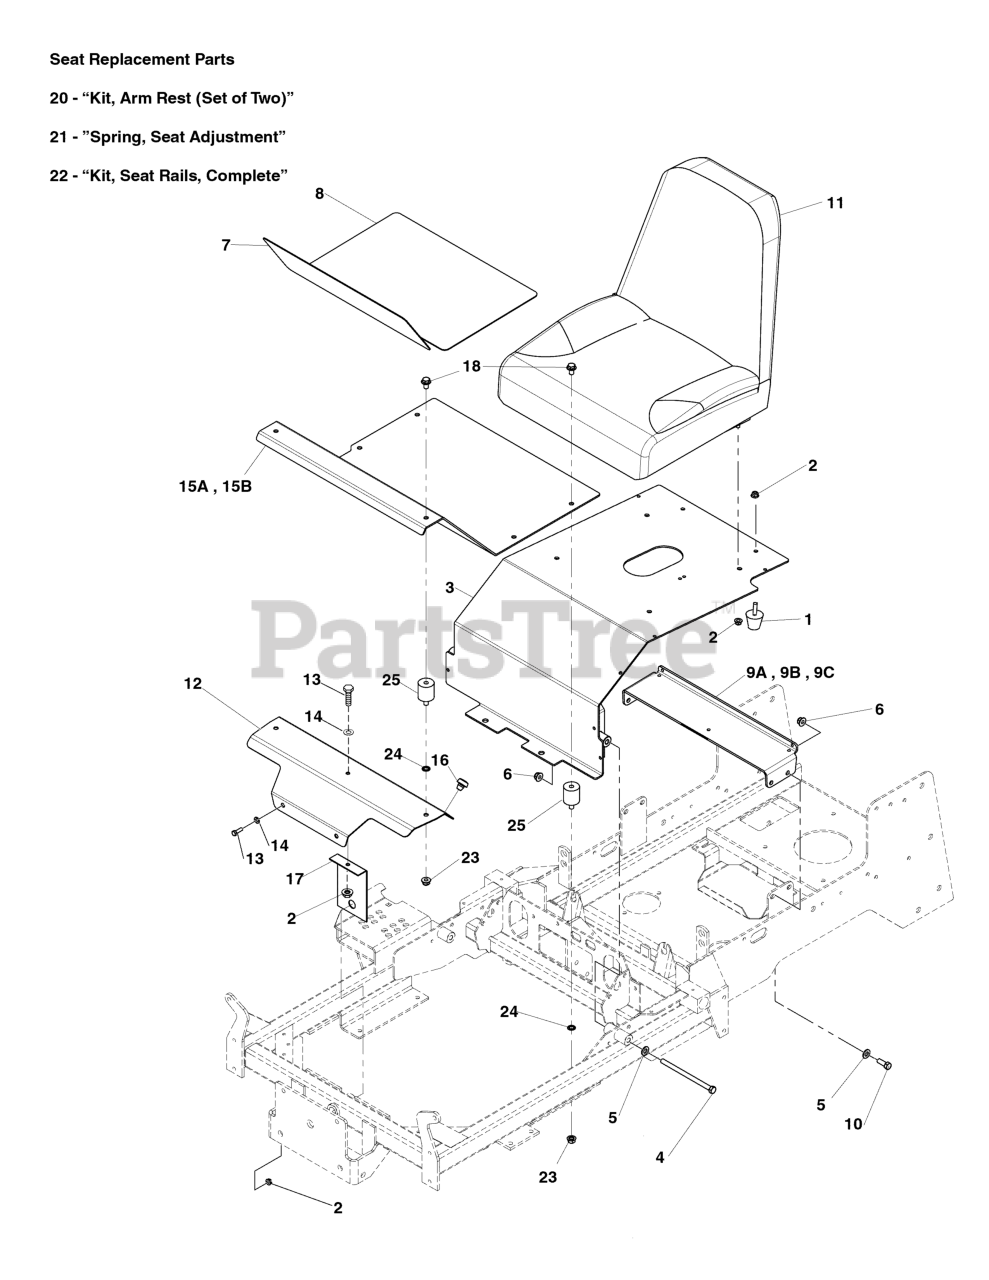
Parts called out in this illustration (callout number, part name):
1	BUMPER, RUBBER 5/16-18
2	NUT, 5/16-18 HEX NYLOCK FLANGE
3	ASSM, SEAT PLATE W/ DECALS
4	BOLT, 3/8-16 X 6" GD5 CZ
5	WASHER, 3/8 SAE
6	NUT, 3/8-16 HEX NYLOCK FLANGE
7	SAFETY WALK, 17.17 X 6.00
8	SAFETY WALK, 17.13 X 11.50
10	BOLT, 3/8-16 X 1" GD5 CZ
11	SEAT, NO ARM REST
12	PLATE, FLOOR PAN, FRONT - IS500Z
13	BOLT, 5/16-18 X 1" GD5 YZ
14	WASHER, 5/16" GD.9 FLAT
16	MNT, VBRTN
17	PLATE, SUPPORT, FRONT FLOOR
18	BOLT, 3/8-18 X 5/8, FLANGE SERRATED
20	KIT, ARM REST
21	SPRING, EXTENSION, SEAT ADJUSTMENT (BLK OR SLVR)
22	KIT, SEAT RAILS
23	NUT, 3/8-16 HEX SERRATED FLANGE
24	WASHER, 3/8" INT TOOTH LOCK
25	MNT, VBRTN, 30 DURO
